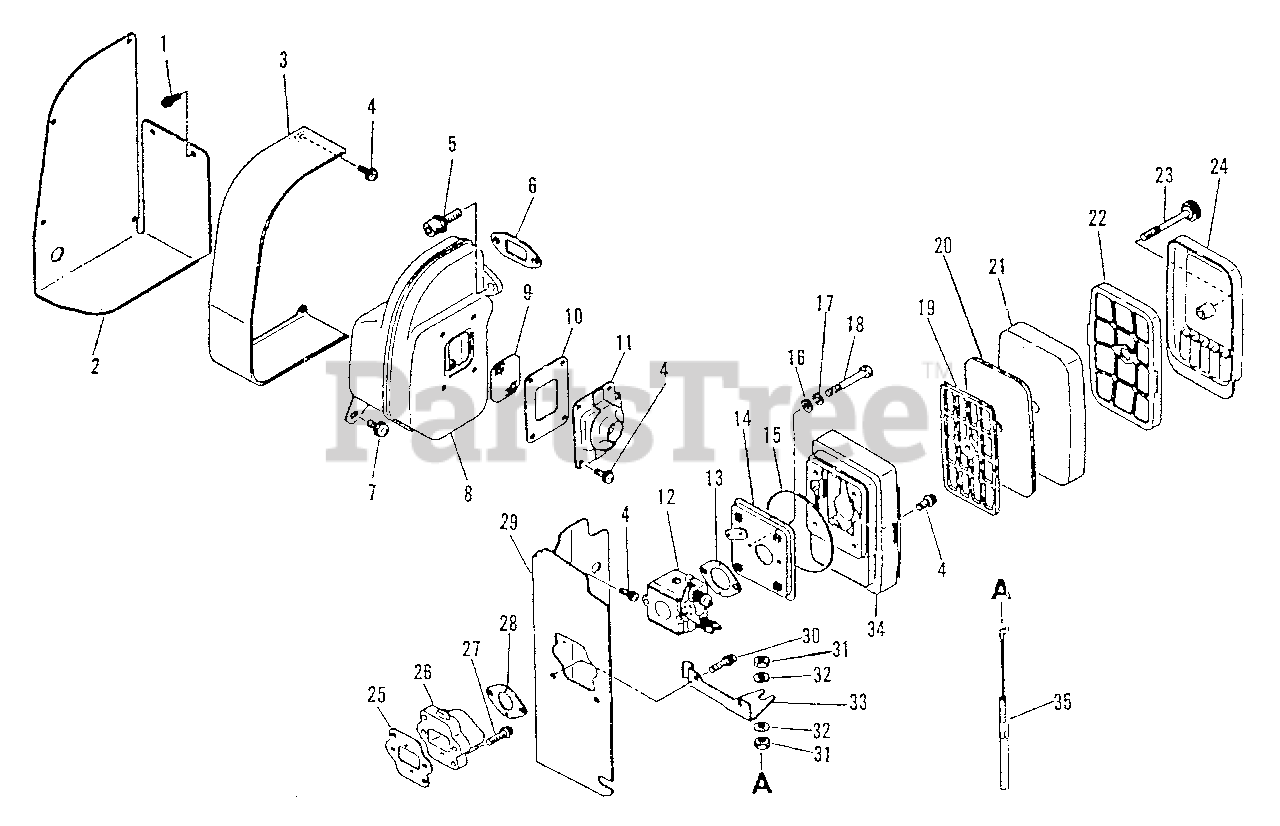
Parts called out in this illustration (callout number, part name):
1	SCREW - 4X14
2	INSULATOR
3	COVER, MUFFLER
4	SCREW - 4X10
5	SCREW - 6X20
6	GASKET, EXHAUST
7	SCREW - 5X10
8	MUFFLER
9	SCREEN, SPARK ARRESTOR
10	GASKET, EXHAUST
11	GUIDE, EXHAUST
12	CARBURETOR C1U-K17
13	GASKET, INTAKE
14	BRACKET
15	O-RING
16	WASHER - 5
17	LOCKWASHER - 5
18	BOLT
19	RETAINER, AIR FILTER
20	FILTER, AIR
21	FILTER, AIR
22	RETAINER, AIR FILTER
23	THUMBSCREW
24	COVER, AIR FILTER - GRAY
25	GASKET, INTAKE
26	INSULATOR, INTAKE
27	SCREW - 5X25
28	GASKET, INTAKE
29	INSULATOR
30	SCREW - 5X20
31	WASHER - 6
33	CLIP
34	CASE, AIR FILTER
35	CABLE, THROTTLE
